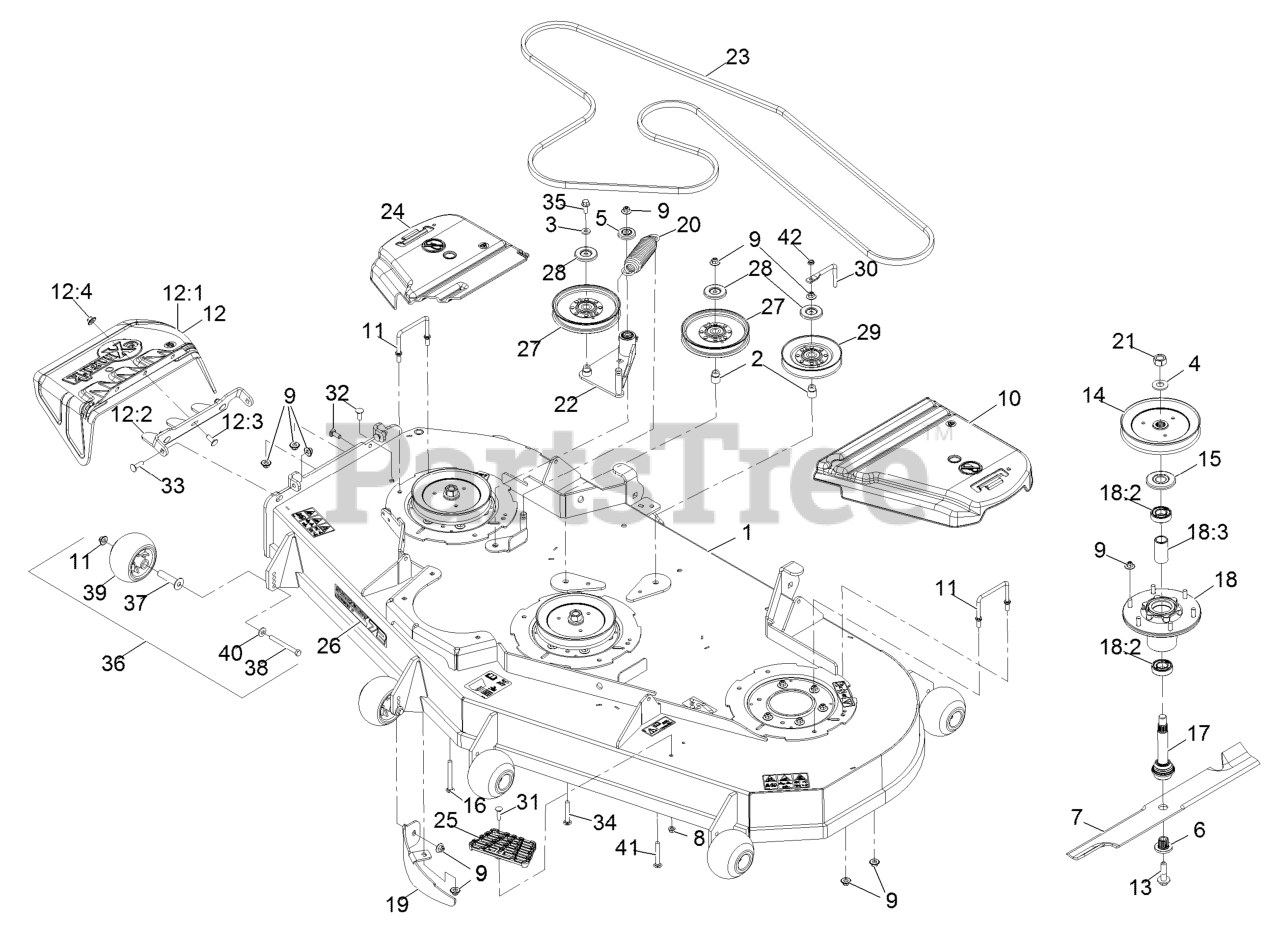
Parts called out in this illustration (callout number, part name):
1	Deck-724
2	Bushing, Idler
4	Washer-Spring Disc 3/4
5	Guard-Top
6	Bushing, Splined
7	Blade, Mulching
7	Blade, Notched (72")
7	Blade-Extreme 2, 24.50"
7	Blade, Low Lift (72")
7	Blade, Solid (72")
8	Nut-Nyloc 5/16-18 Flg
9	Nut-Nyloc 3/8-16 Flg
10	Cover-Belt, LH
11	Wireform-Cover
12	ASM,Discharge Chute
12:1	Chute, Discharge
12:2	Bracket,Discharge Chute
12:3	Bolt-Carriage 3/8-16 X 1
12:4	Nut-Nyloc 3/8-16 Flg
13	Screw-Sems 1/2-20 X 2.19
14	Sheave,Blade Drive 7.25
15	Guard,Bearing Top .989
16	Bolt-Carriage Shoulder 3/8-16 X 3 1/2
17	ASM-Spindle And Seal
18	ASM-Cutter Hsg With Bearings
18:2	Bearing-Ball
18:3	Spacer-Bearing
19	Baffle-Dogleg, Lz72
20	Spring-Extension
21	Nut-Hex
22	Idler Arm ASM
24	Shield-Belt
25	Step-Deck
26	Decal, 724
27	Idler-Pulley
28	Shield-Dust
29	Idler V
30	Guide-Belt
31	Bolt-Carriage 5/16-18 X 1 1/4
32	Bolt-Carriage 3/8-16 X 1
33	Bolt-Carriage 3/8-16 X 1 1/4
34	Bolt-Carriage 3/8-16 X 2 1/2
35	Screw-HH Flg 3/8-16 X 1
36	Kit, Anti-Scalp Roller
37	Axle, Roller
38	Screw-HH 3/8-16 X 3 3/4
39	Roller-Anti-Scalp
40	Washer-Spring Disc 3/8
41	Bolt-Carriage 3/8-16 X 2 3/4
42	Nut-Nyloc 3/8-16 Thin
